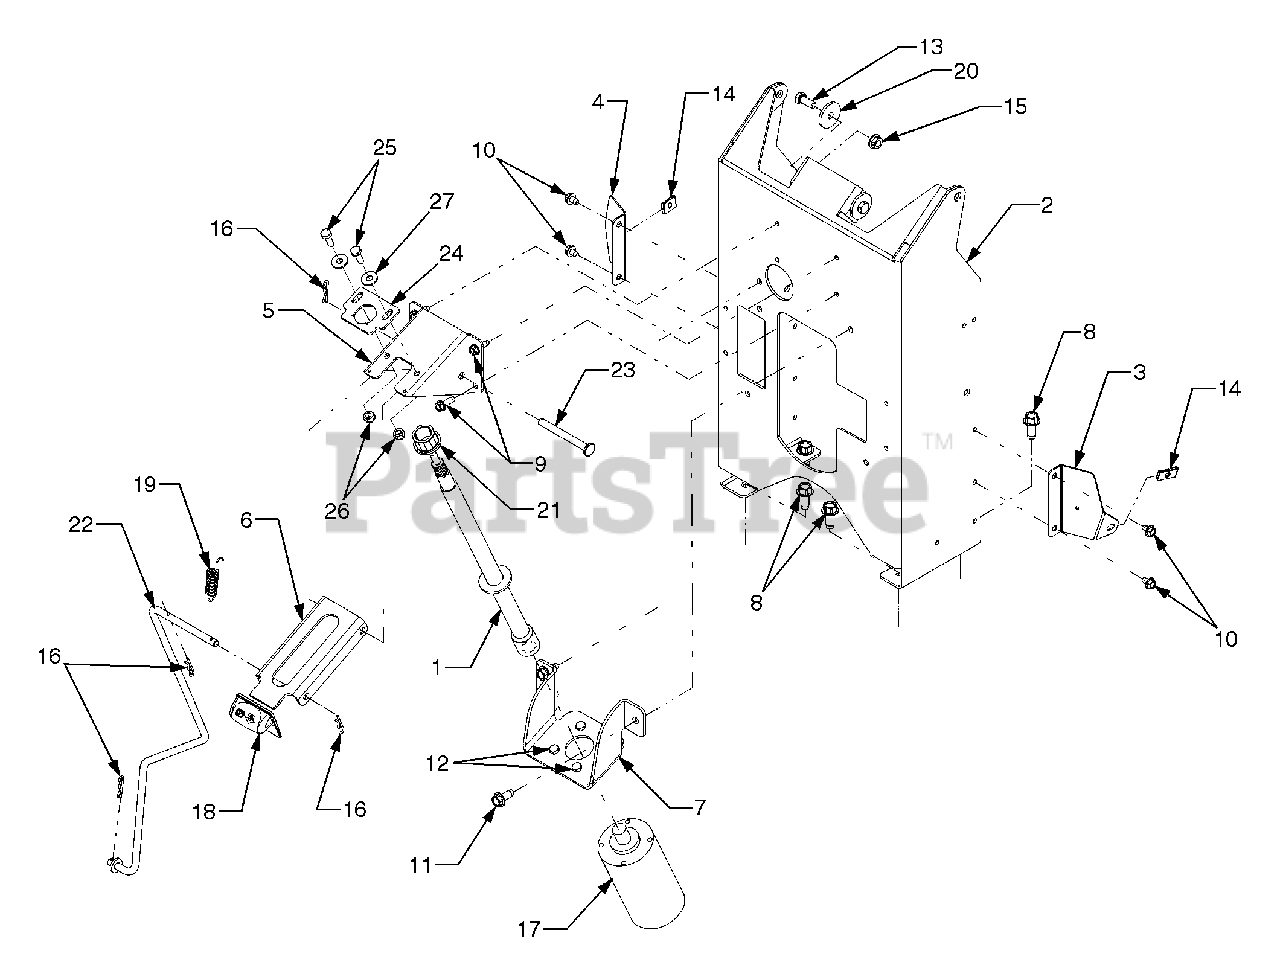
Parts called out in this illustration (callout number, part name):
1	Shaft, Steering
3	Bracket, Dash Mtg. RH
4	Bracket, Dash Mtg. LH
9	Screw, Hex Wash, Hd Tapp 1/4-20 x .75
10	Screw, Hex Wash, Hd Tapp 1/4-20 x .375
11	Screw, Hex Wash, Hd Tapp 5/16-18 x .75
12	Screw, Hex, M6-1 x 16 Hardened
13	Screw, Hex Cap 5/16-18 x .75
14	Nut, Speed, 1/4-20
15	Nut, Hex Flange Lock, 5/16-18
16	Pin, Internal Cotter
17	Pump, Hydraulic Steering
18	Lever, Parking Brake
19	Spring, Extension
20	Washer, Flat, .33 x 1.25 x .12 .
21	Bearing, Hex Flange, .75 ID
22	Rod, Parking Brake
23	Pin, Parking Brake Pivot
26	Nut, Hex Insert Lock, 1/4-20
27	Washer, Flat, .28 x .74 x .063
